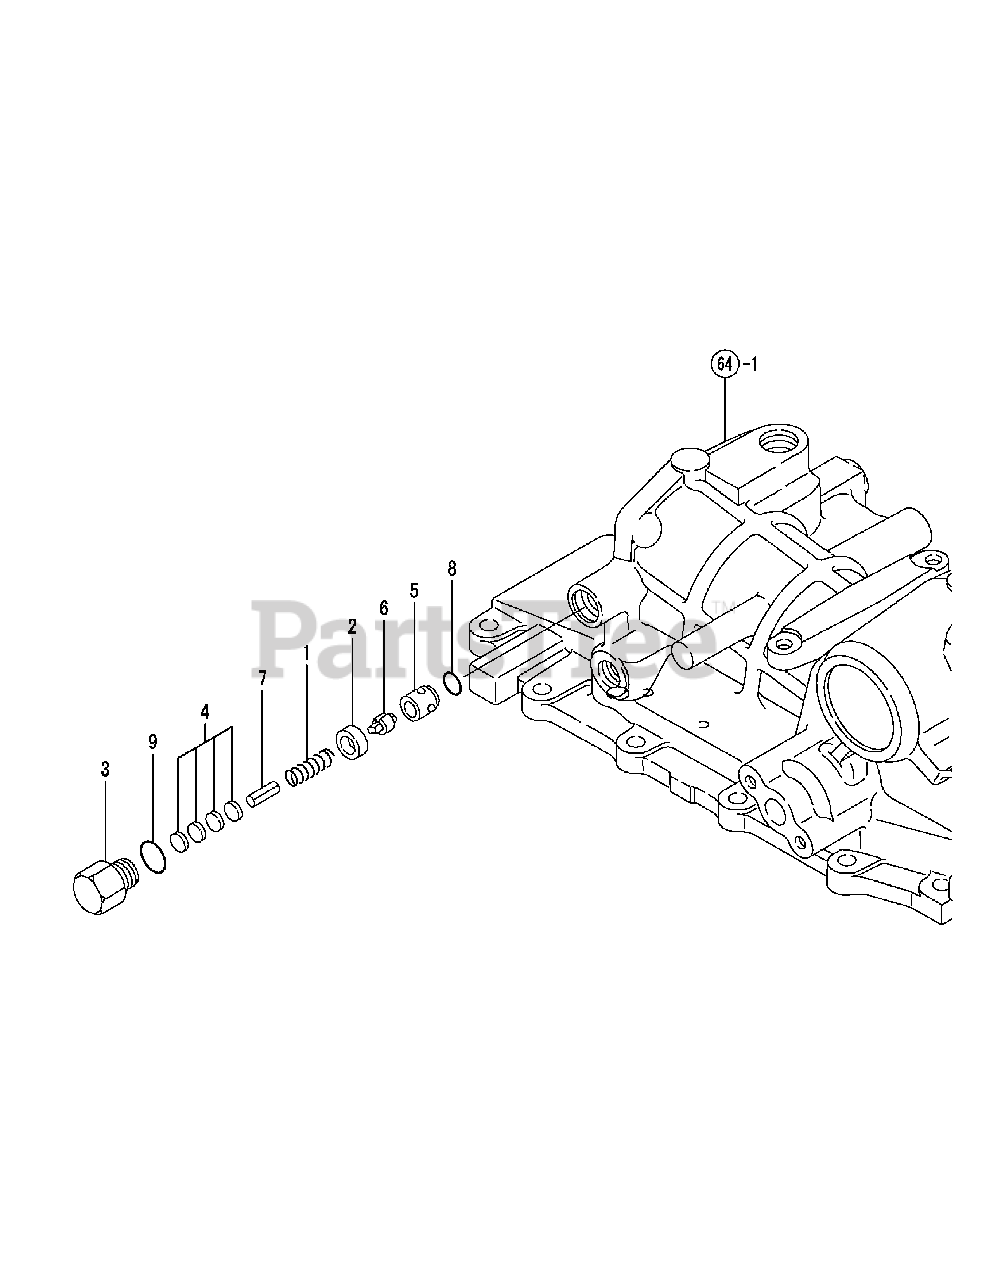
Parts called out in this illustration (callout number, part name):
1	SPRING, RELIEF VALVE
3	PLUG, SAFETY VALVE
5	SEAT, SAFETY VALVE
6	POPPET, SAFETY VALVE
7	SPRING PIN 6X28
8	PACKING, P 12.0
9	O-RING 1A P-18.0
